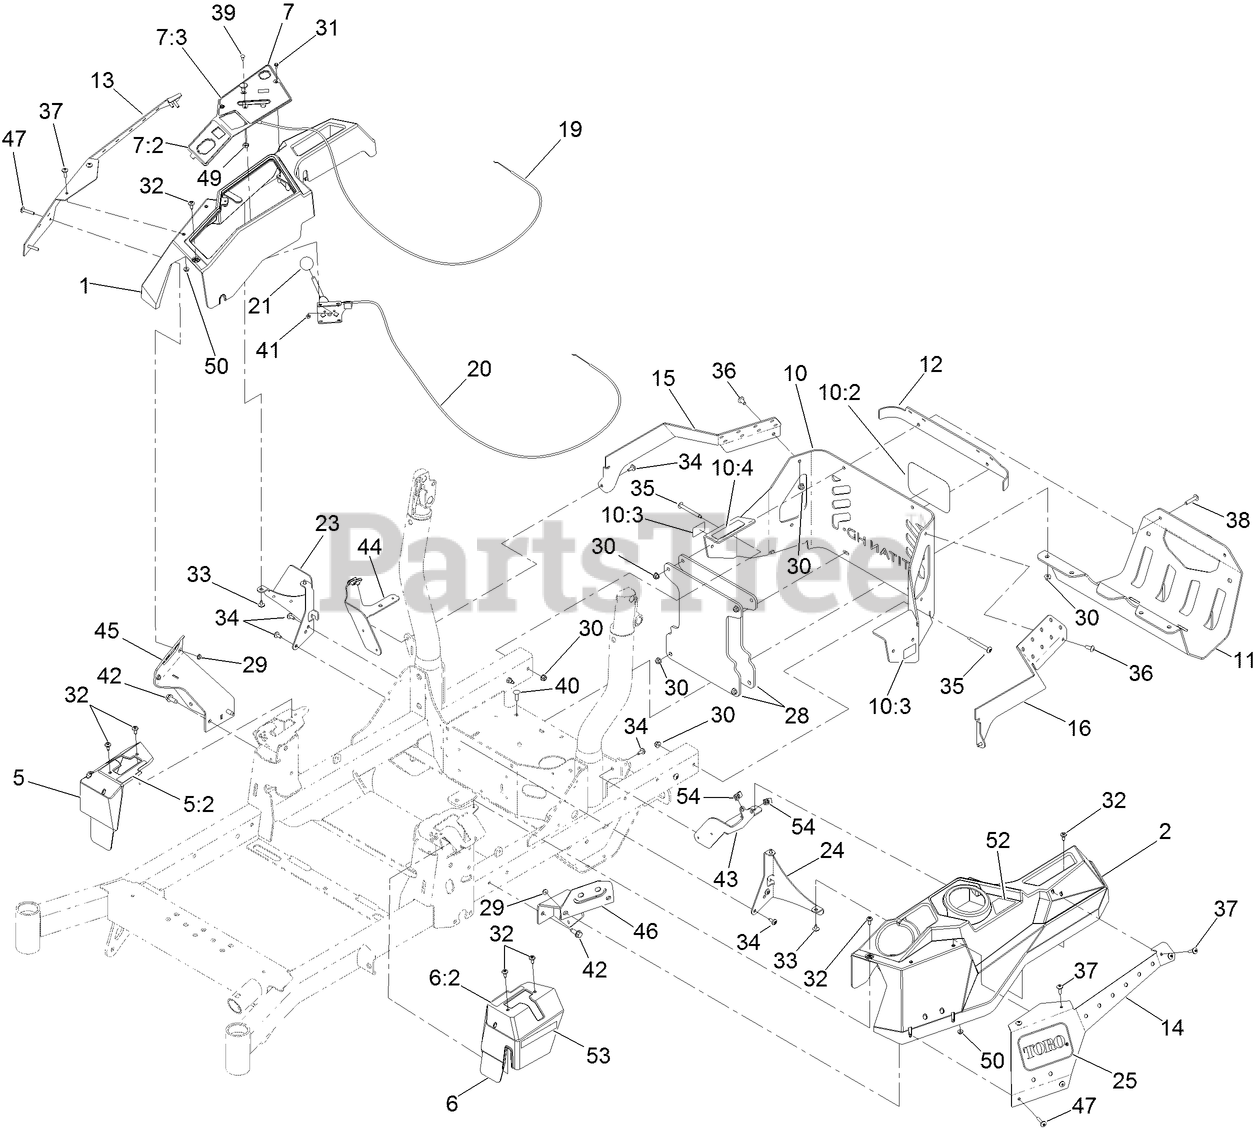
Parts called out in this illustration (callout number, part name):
1	CONSOLE-RH
2	CONSOLE-LH
5	COVER-CONTROL, MOTION (RH)
5:2	DECAL-CONTROL, MOTION (RH)
6	COVER-CONTROL, MOTION (LH)
6:2	DECAL-CONTROL, MOTION (LH)
7	CONTROL PANEL ASM
7:2	DECAL-PANEL, CONTROL
7:3	DECAL-PANEL, CONTROL
10	REAR GUARD ASM
10:2	DECAL
10:3	DECAL-WARNING
10:4	DECAL-ARRESTOR, SPARK
11	GUARD-MUFFLER
12	TRIM-UPPER, REAR
13	COVER-POD, RH
14	COVER-LH
15	BRACKET-GUARD, RH
16	BRACKET-GUARD, LH
19	CABLE-CONTROL, CHOKE
20	CABLE-CONTROL, THROTTLE
21	KNOB-BALL
23	SUPPORT-CONSOLE, RH
24	BRACKET-CONSOLE, LH
25	DECAL
28	WEIGHT-REAR
29	NUT-HF
30	NUT-HF, NI
31	SCREW-HWH
32	SCREW-SHOULDER
33	SCREW-TORX
34	SCREW-TORX
35	SCREW-TORX
36	SCREW-TORX
37	SCREW-TRUSS
38	SCREW-TORX
39	BOLT-CARR
40	SCREW-CARR
41	NUT-LOCK, NI
42	SCREW-FORMING, THREAD
43	BRACKET-SUPPORT, LEFT POD
44	BRACKET-SUPPORT, RIGHT POD
45	BRACKET-SUPPORT, POD (RH)
46	BRACKET-SUPPORT, POD (LH)
47	SCREW-TRUSS
49	NUT-HJ
50	NUT-KEPS
52	DECAL-FILL, FUEL
54	NUT-RETAINER
